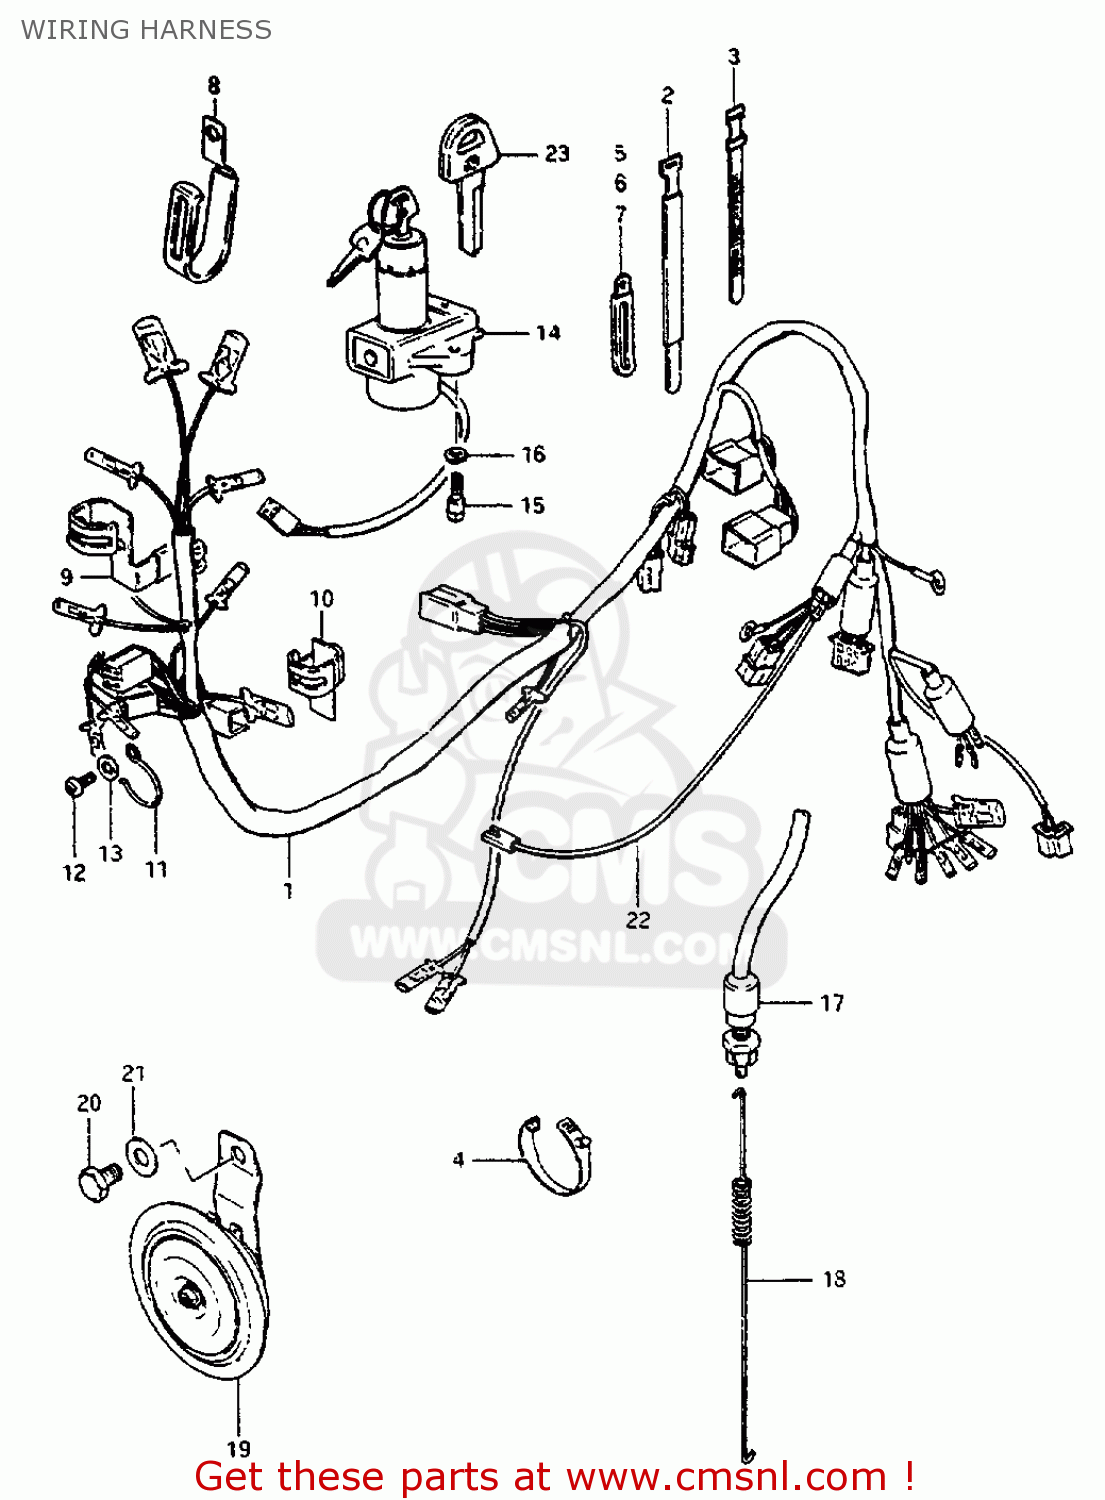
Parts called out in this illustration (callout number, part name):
1	WIRING HARNESS
2	CLAMP
3	CLAMP(L:120)
4	CLAMP,L:88
5	CLAMP
6	CLAMP
7	CLAMP
8	CLAMP,WIRING HARNESS
9	CLAMP,WIRING HARNESS
10	CLAMP,WIRING HARNESS
11	GUIDE,WIRING HARNESS
12	SCREW 6X12
13	WASHER
14	SWITCH ASSY,IGNITION
15	BOLT
16	LOCK WASHER
17	SWITCH ASSEMBLY,STOP LAMP
18	SPRING
19	HORN ASSEMBLY
20	BOLT 8X12
21	WASHER
22	WIRE
23	KEY,BLANK
